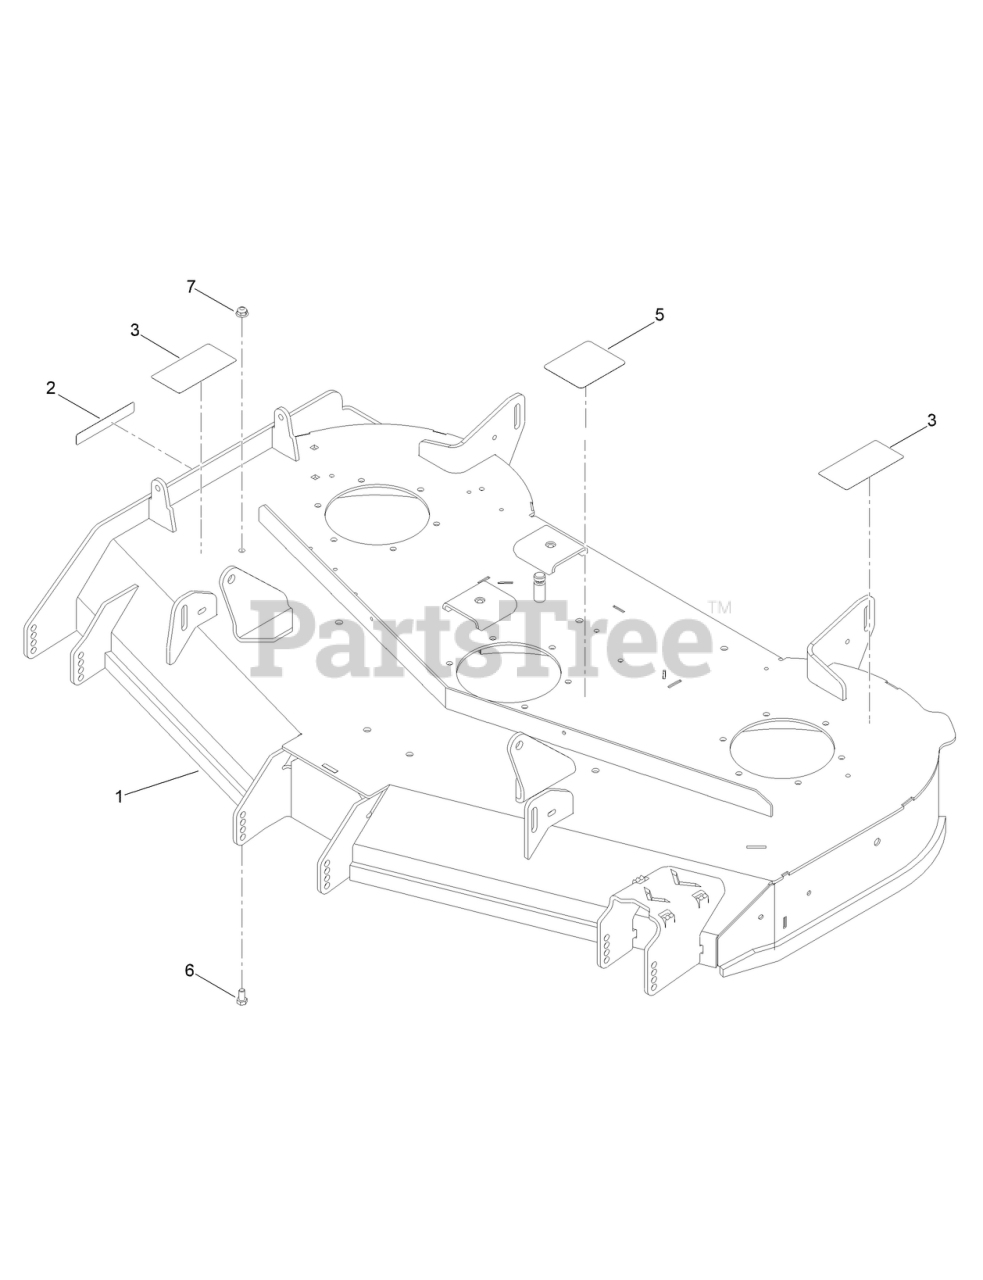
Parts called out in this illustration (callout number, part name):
2	DECAL-DANGER
3	DECAL-DANGER, DECK
5	DECAL-BELT ROUTING
6	SCREW-HH
7	NUT-HF
